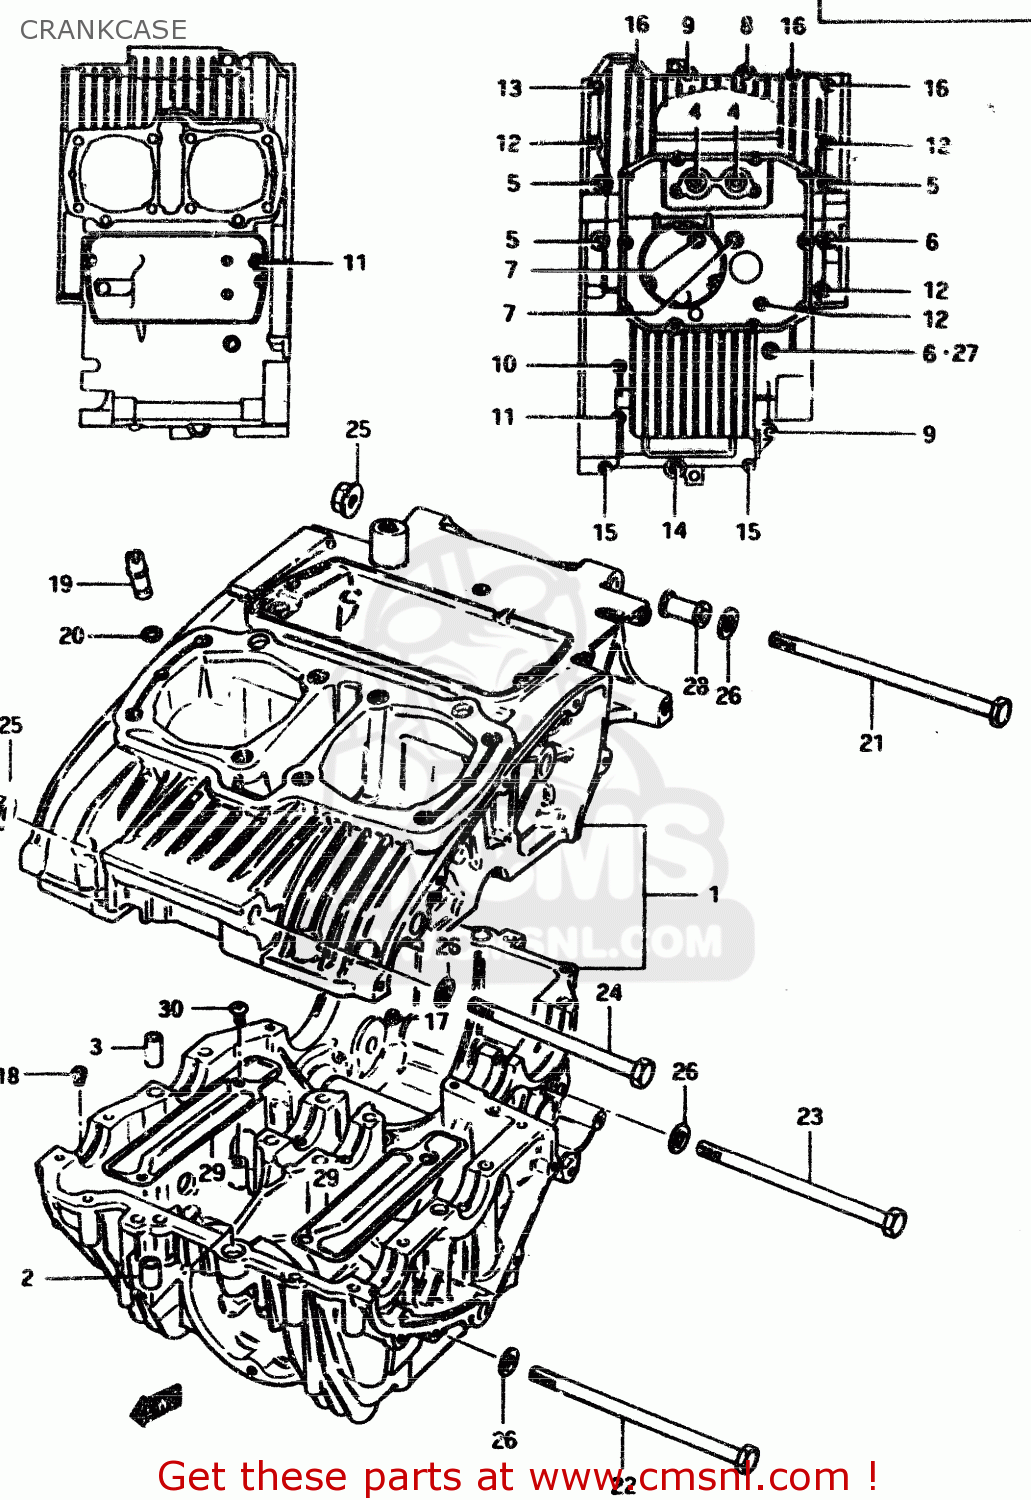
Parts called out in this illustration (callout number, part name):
1	CRANKCASE SET
2	PIN(10.4X13X22)
3	PIN (11X20)(SUS)
4	BOLT
5	BOLT
6	BOLT
7	BOLT
8	BOLT (8X65)
9	BOLT
10	BOLT
11	BOLT
12	BOLT (6X90)
13	BOLT
14	BOLT
15	BOLT
16	BOLT (6X45)
17	JET,AIR
18	JET
19	JET
20	O RING(D:1.05,ID:3.1)
21	BOLT
22	BOLT
23	BOLT
24	BOLT
25	NUT 10MM
26	WASHER
27	GASKET 8.2X14X1 (NAS)
28	SPACER,ENGINE MOUNT
29	PLATE,OIL SEPARATOR
30	SCREW
